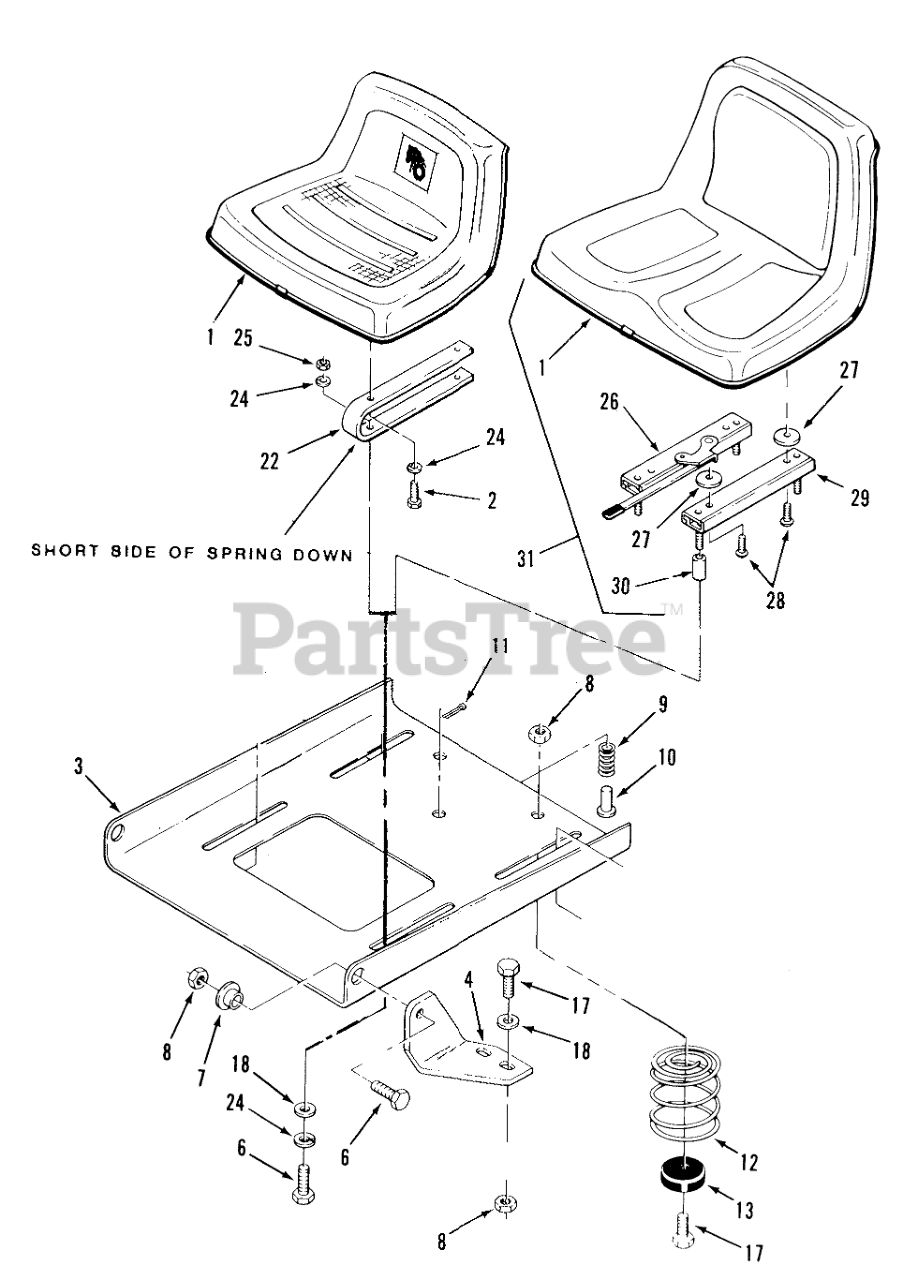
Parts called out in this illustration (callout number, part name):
1	Seat
2	Bolt
3	PLATE-SEAT PIVOT B
4	BRACKET-PIVOT L.H B
6	HHCS
7	BUSHING
8	Nut
9	SPRING-SEAT SWITCH
11	Cotter Pin
12	SPRING
13	BUMPER
17	Bolt
18	WASHER 5/16 SAE
22	Seat Spring
24	Lockwasher
25	Nut
26	ADJUSTER-SEAT RH
27	SPACER-NYLON
28	Screw
29	ADJUSTER-SEAT LH
30	SPACER
31	Deluxe Seat Assembly
